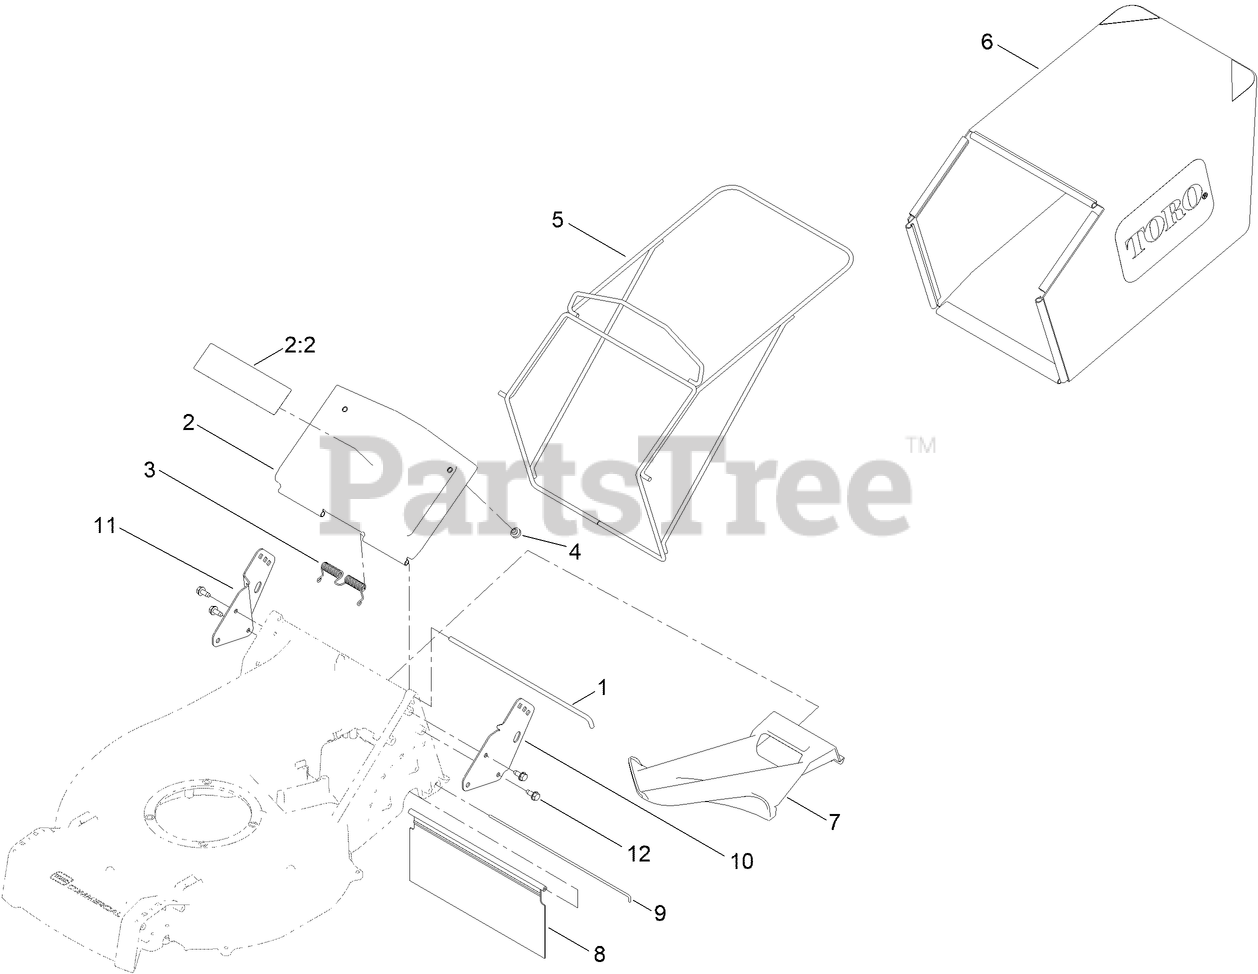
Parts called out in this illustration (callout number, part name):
1	ROD-DOOR, BAG
2	BAG DOOR ASM
2:2	DECAL-WARNING
3	SPRING-TORSION
4	BUMPER
5	FRAME-BAG
6	BAG-GRASS, ASM
7	PLUG-MULCH
8	SHIELD-TRAILING
9	ROD-SHIELD, TRAILING
10	BRACKET-MOUNT, HANDLE (LH)
11	BRACKET-MOUNT, HANDLE (RH)
12	SCREW-HWHTF
